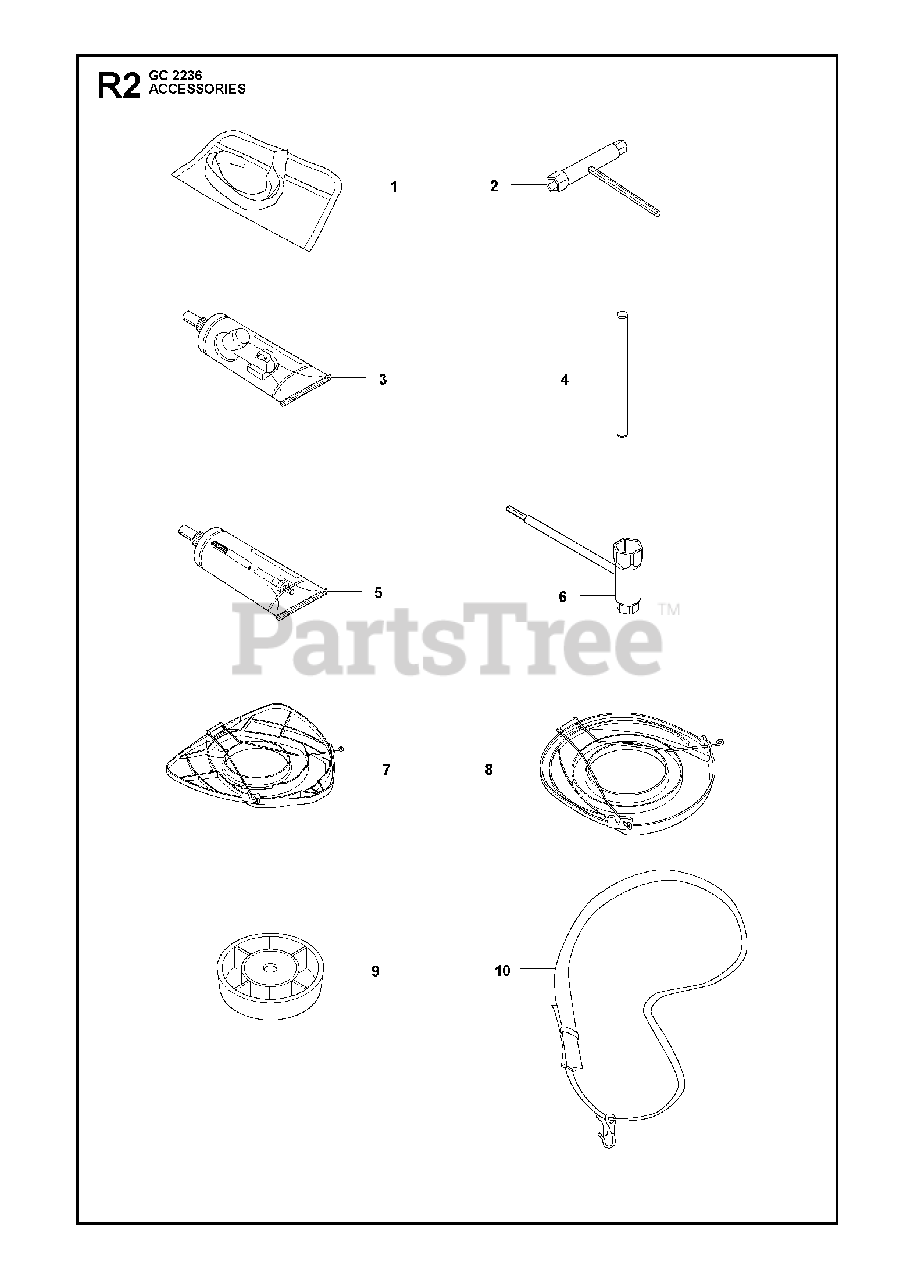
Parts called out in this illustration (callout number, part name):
2	COMB.TOOL 8-10-14
4	LOCKING PIN
6	RP COMBI TOOL
7	TRANSPORT GUARD
8	BLADE GUARD TRANSPORT
9	SUPPORT CUP
10	STRAP
10	SHOULDER STRAP WITH SIGN
